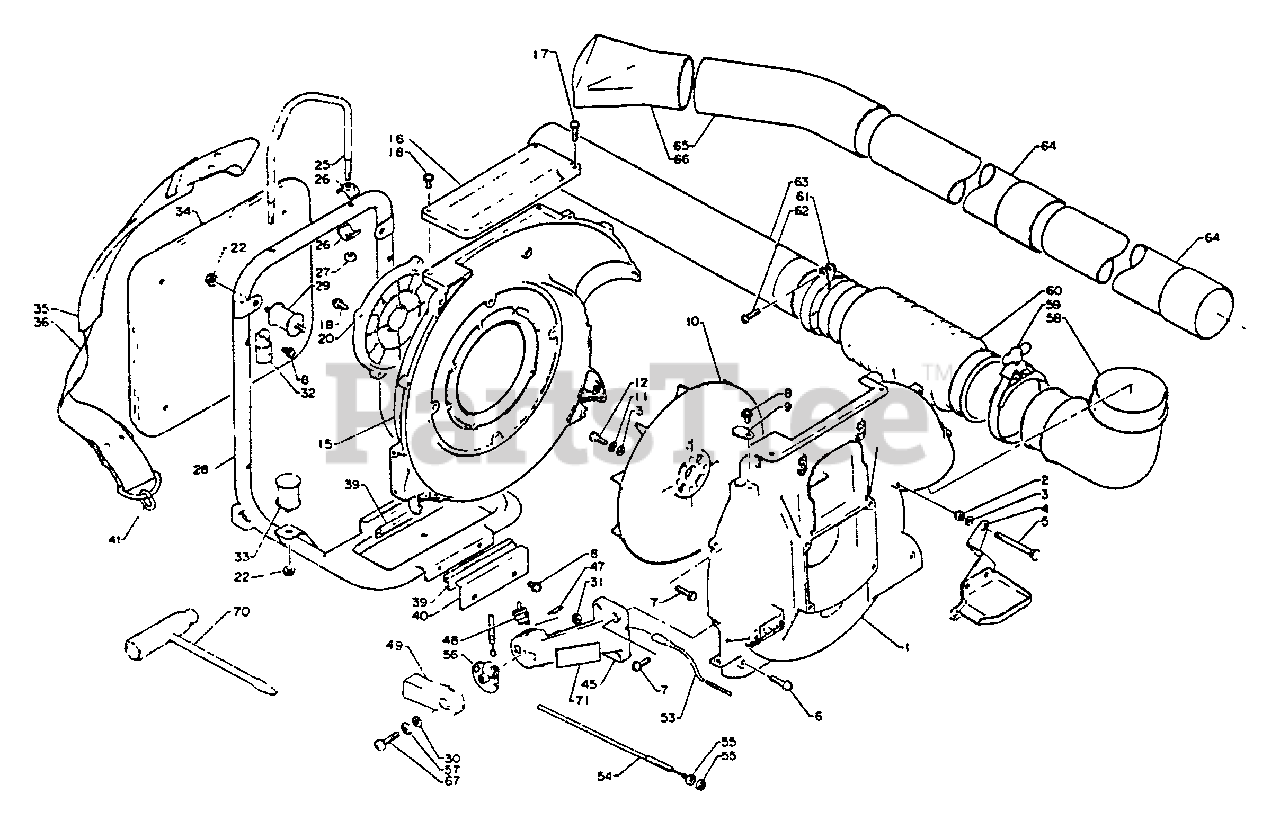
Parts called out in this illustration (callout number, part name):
1	COVER, FAN - OUTER
2	NUT - 5
3	WASHER - 5
4	BRACKET, MUFFLER COVER
5	BOLT, ELBOW
6	SCREW - 5X25
7	SCREW - 5X20
8	SCREW - 5X10
9	PLUG
11	LOCKWASHER - 5
12	BOLT - 5X16
15	COVER, FAN - INNER -- ORANGE
16	PLATE
17	SCREW - 6X20
18	SCREW - 6X15
20	GUARD, DEBRIS
22	NUT - 6 -- FLANGE
27	LOCKNUT - 6
28	FRAME, BACKPACK
30	WASHER - 6
31	LOCKNUT - 6
32	BRACKET, CUSHION
34	CUSHION
35	BACKPACK STRAP ASSY
36	BACKPACK STRAP ASSY
39	CUSHION, FUEL TANK
40	BRACKET, FUEL TANK
41	RING, STRAP
45	MOUNT, THROTTLE LEVER
47	LABEL - STOP
48	IGNITION SWITCH ASSY
49	TRIGGER, THROTTLE
53	LEAD - GROUND
54	CABLE, THROTTLE
57	WASHER
58	TUBE, BLOWER - ELBOW
59	CLAMP
60	TUBE, BLOWER - FLEXIBLE
61	CLAMP
62	SCREW - 5X20
63	TUBE, BLOWER - SWIVEL
64	TUBE, BLOWER - STRAIGHT
65	TUBE, BLOWER - CURVED
66	NOZZLE - FAN HEAD
67	SCREW - 6X25
70	T-WRENCH - 10X19mm
71	LABEL - CAUTION
74	LABEL - ECHO
75	LABEL - NOISE
